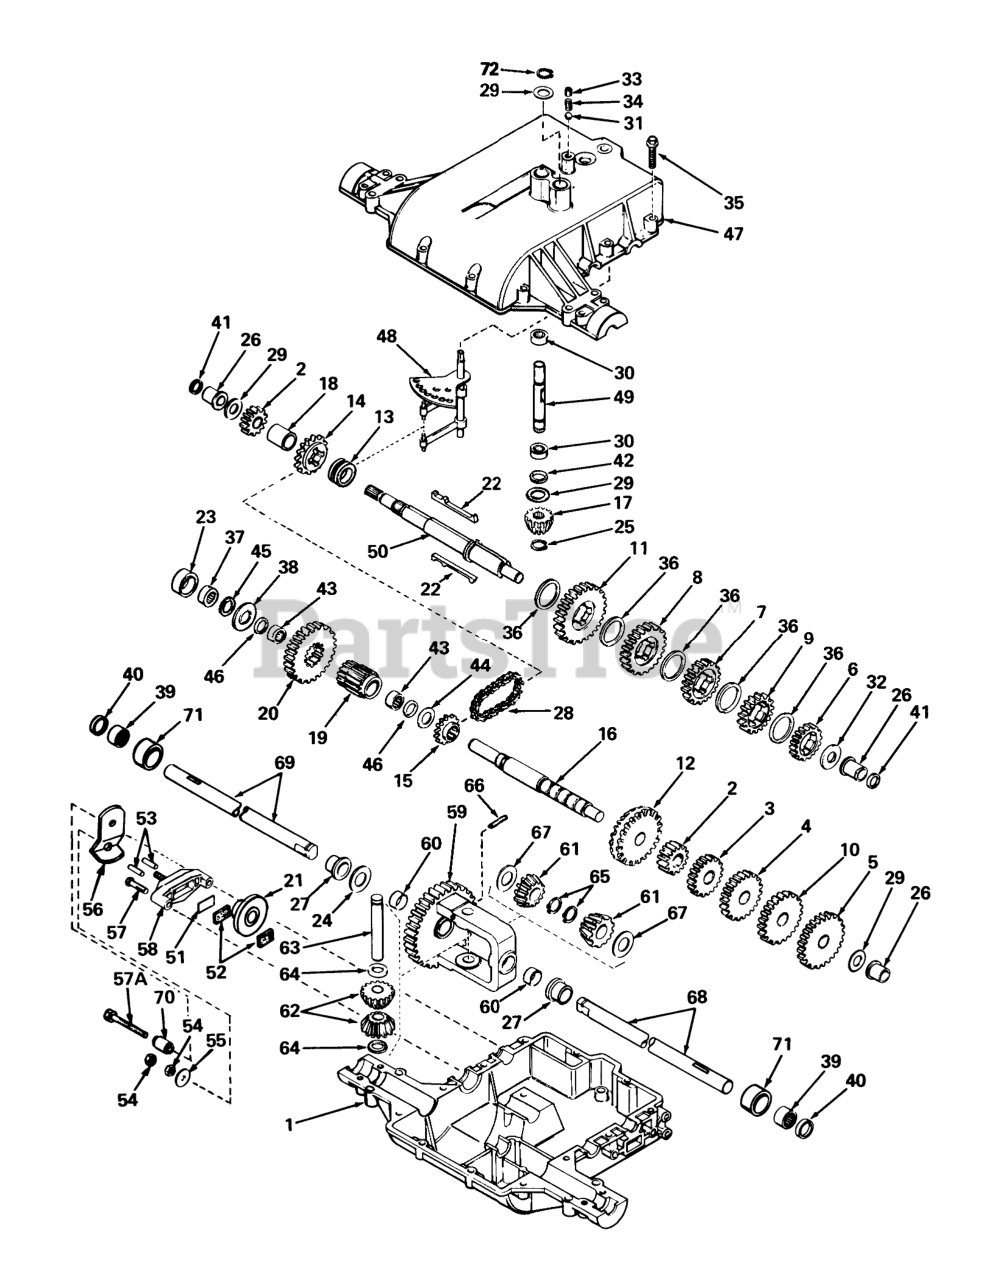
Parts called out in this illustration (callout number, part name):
1	Case, Transaxle
2	Gear-Spur 15 Teeth
3	Gear, Spur (20 teeth)
4	Gear, Spur (25 teeth)
5	Gear, Spur (30 teeth)
6	Gear-Spur 20 teeth
7	Gear, Spur (25 teeth)
8	Gear, Spur (30 teeth)
9	ASpur Gear (22 Teeth)
10	Gear, Spur (28 teeth)
11	Gear-Spur, 35 Teeth
12	Gear, Bevel (42 teeth)
13	Collar-Shift
14	Sprocket-18 Teeth
15	Sprocket-9 Teeth
16	Shaft-Counter
17	Bevel Pinion-Input
18	Spacer
19	Pinion-Output
20	Gear-Output
23	Spacer
24	Washer
25	Ring-Retainer
26	Bushing, Flanged
27	Bushing, Flanged
28	Chain-Roller #41
29	Washer
30	Bearing-Needle
31	Ball-Steel
32	Washer
33	Screw-Set
34	Spring
35	Ring Set (.020 O S)
36	Washer
37	Bearing-Needle
38	Washer-Flat
39	Bearing-Cartridge
40	Seal Oil
41	Ring-Square Cut
42	O Ring
43	Bearing-Needle
44	Washer-Flat
45	Ring-Square Cut
46	Ring-Square Cut
47	Cover-Transaxle
48	Rod & Fork Assembly
49	Shaft, Input
50	Shaft, Brake
51	Brake Pad Plate
52	Brake Pad
53	Dowel Pin
54	Locknut
55	Washer
56	Lever-Brake
57	Ring Set (.020 O S)
57A	Screw-Hex. Flange
58	Holder-Brake Pad
59	Gear Assy., Differential (Incl. 2 of No. 60)
60	Bushing
61	Bevel Gear
62	Gear Pinion
63	Drive Pin
64	Thrust Washer
65	Ring-Snap
66	Pin-Roll
67	Washer
68	Axle (14 7/8" long)
69	Axle (13" long)
70	Spacer
71	Sleeve
72	Ring-Snap
